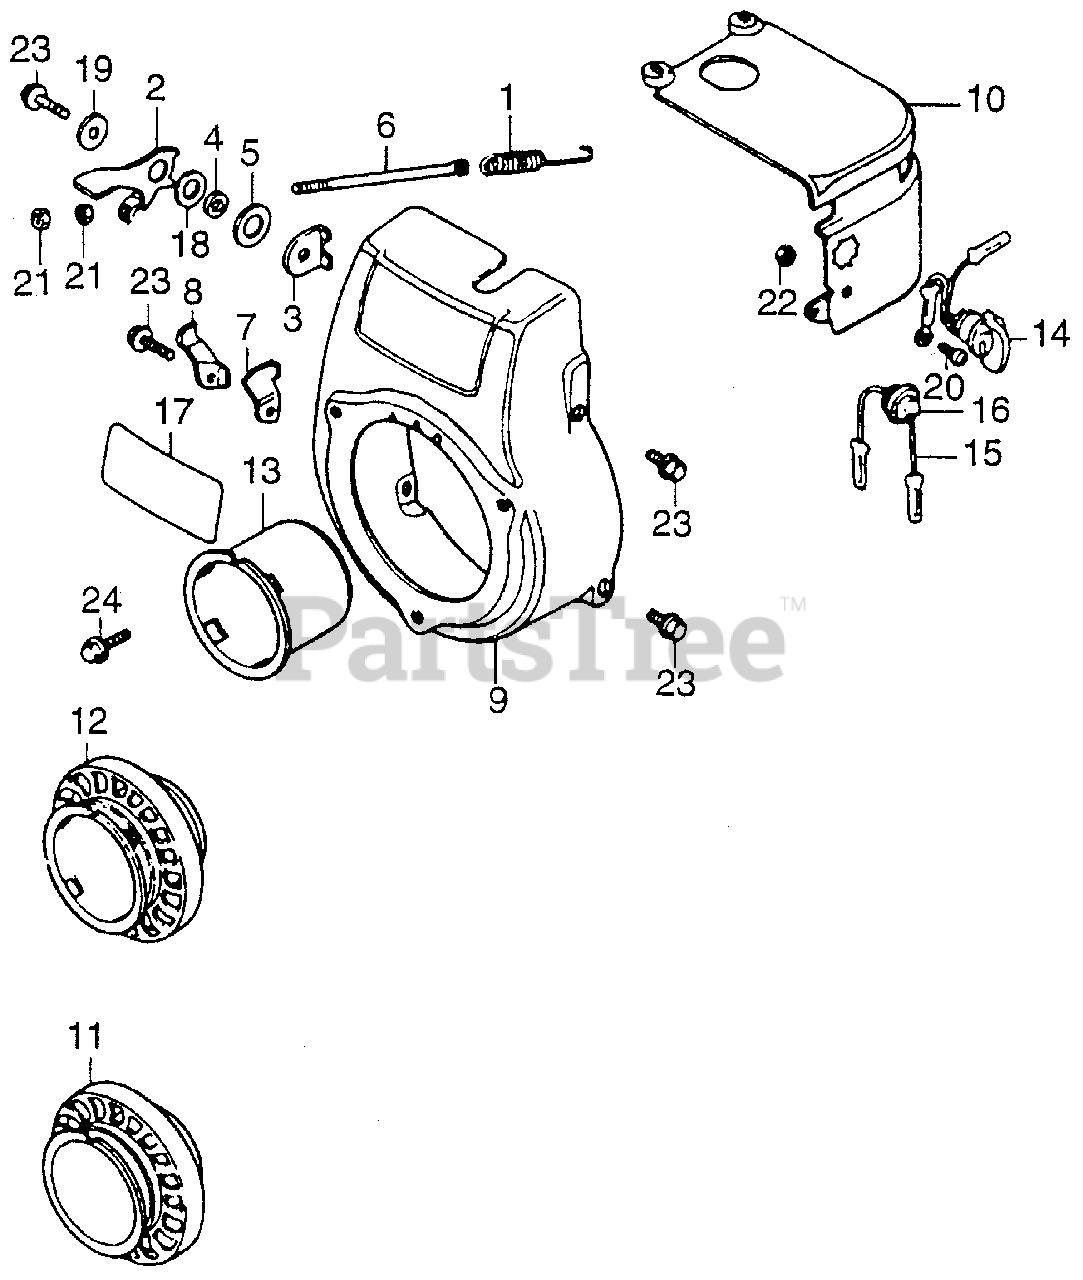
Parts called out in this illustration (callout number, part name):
1	SPRING, GOVERNOR
2	LEVER, CONTROL
3	STOPPER, LEVER
4	SPACER, LEVER
5	SPRING, LEVER
6	ROD, ADJUSTING
7	STAY A, THROTTLE CABLE
8	STAY B, THROTTLE CABLE
9	COVER, FAN *R8* (BRIGHT RED) (NOT AVAILABLE)
10	COVER, SIDE *R8* (BRIGHT RED)
11	PULLEY, STARTER
12	PULLEY, STARTER
13	PULLEY, STARTER (NOT AVAILABLE)
14	SWITCH ASSY., ENGINE STOP
15	WIRE A, ENGINE SWITCH
16	GROMMET, COVER (NOT AVAILABLE)
17	PLATE, DESCRIPTION
18	WASHER, THROTTLE LEVER (NOT AVAILABLE)
19	WASHER (6.5X20)
20	SCREW, PAN (5X8)
21	NUT, HEX. (4MM)
22	NUT, HEX. (5MM)
23	BOLT, FLANGE (6X12)
24	BOLT, FLANGE (6X16)
